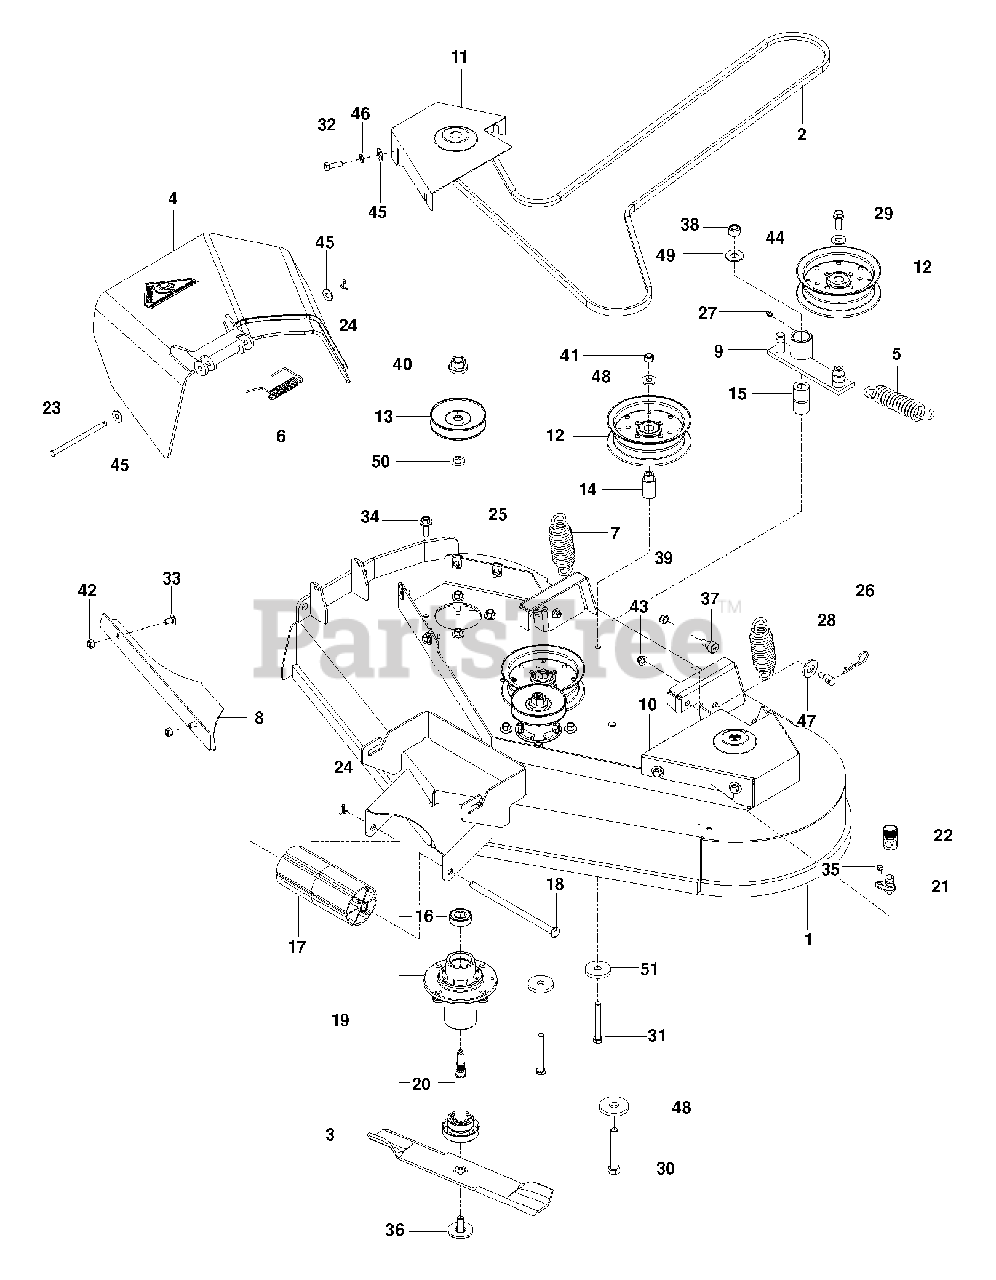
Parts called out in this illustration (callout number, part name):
1	DECK SVC W/DECALS 42 RZ ORANGE
3	BLADE, 14 5/8"
4	DISCHARGE CHUTE 42"
6	SPRING - TORSION
8	CONFINEMENT.PLATE.42".BLACK
10	BELT SHIELD, LEFT 42, ORG
11	BELT SHIELD, RIGHT 42, ORG
12	PULLEY, IDLER
13	PULLEY, MADREL 3.70 OP
14	IDLER BUSHING
15	PIVOT BUSHING
17	NOSE ROLLER 48"
18	ROD.ROLLER.NOSE.NARROW.48"
19	MANDREL.DECK.ASSEMBLY
20	SHAFT ASM MANDREL
21	PORT.WASHOUT
22	COUPLING.QUICK CONNECT
23	PIN-CLEVIS 5/16 DIA X 5.19 ZD
24	COTTER PIN
25	U-CLIP 5/16-18 NUT RETAINER
26	HAIRPIN #4
27	ZERK
28	STUD.FASTNER.W/ANTI-ROTATE
29	4CS 3/8C X 1 SERRATED HEAD
30	HCS 1/2C X 3 1/4
31	BOLT.HEX.FIN.3/8-16 X 3.GR5
32	BOLT.FIN.HEX.5/16-18UNC X 1.00
33	BOLT
34	SCREW, WASHER HEAD
35	SCREW
36	BOLT.WASHER.ASM.7/16-2
37	SB 3/8-16 X 3/8 SKT HD ZD
38	RP NUT 1/2-13 HEX NYLOC ZD
39	5/16-18 NYLOC FLANGE NUT
40	NUT.FLANGE.LOCK.TOP
41	NUT 3/8-16 NYLOC
42	NUT.71038.31-18.HEX.NYLOCK
43	NUT HEX 3/8-16 NYLON, THIN
44	WASHER 3/8 FLAT
45	WASHER
46	WASH.5/16.SLW.ZD
47	WASHER
48	WASHER, SUPPORT
49	WASHER 1/2 FLAT
50	WASHER.SPACER.MANDREL
51	SPINDLE WASHER
